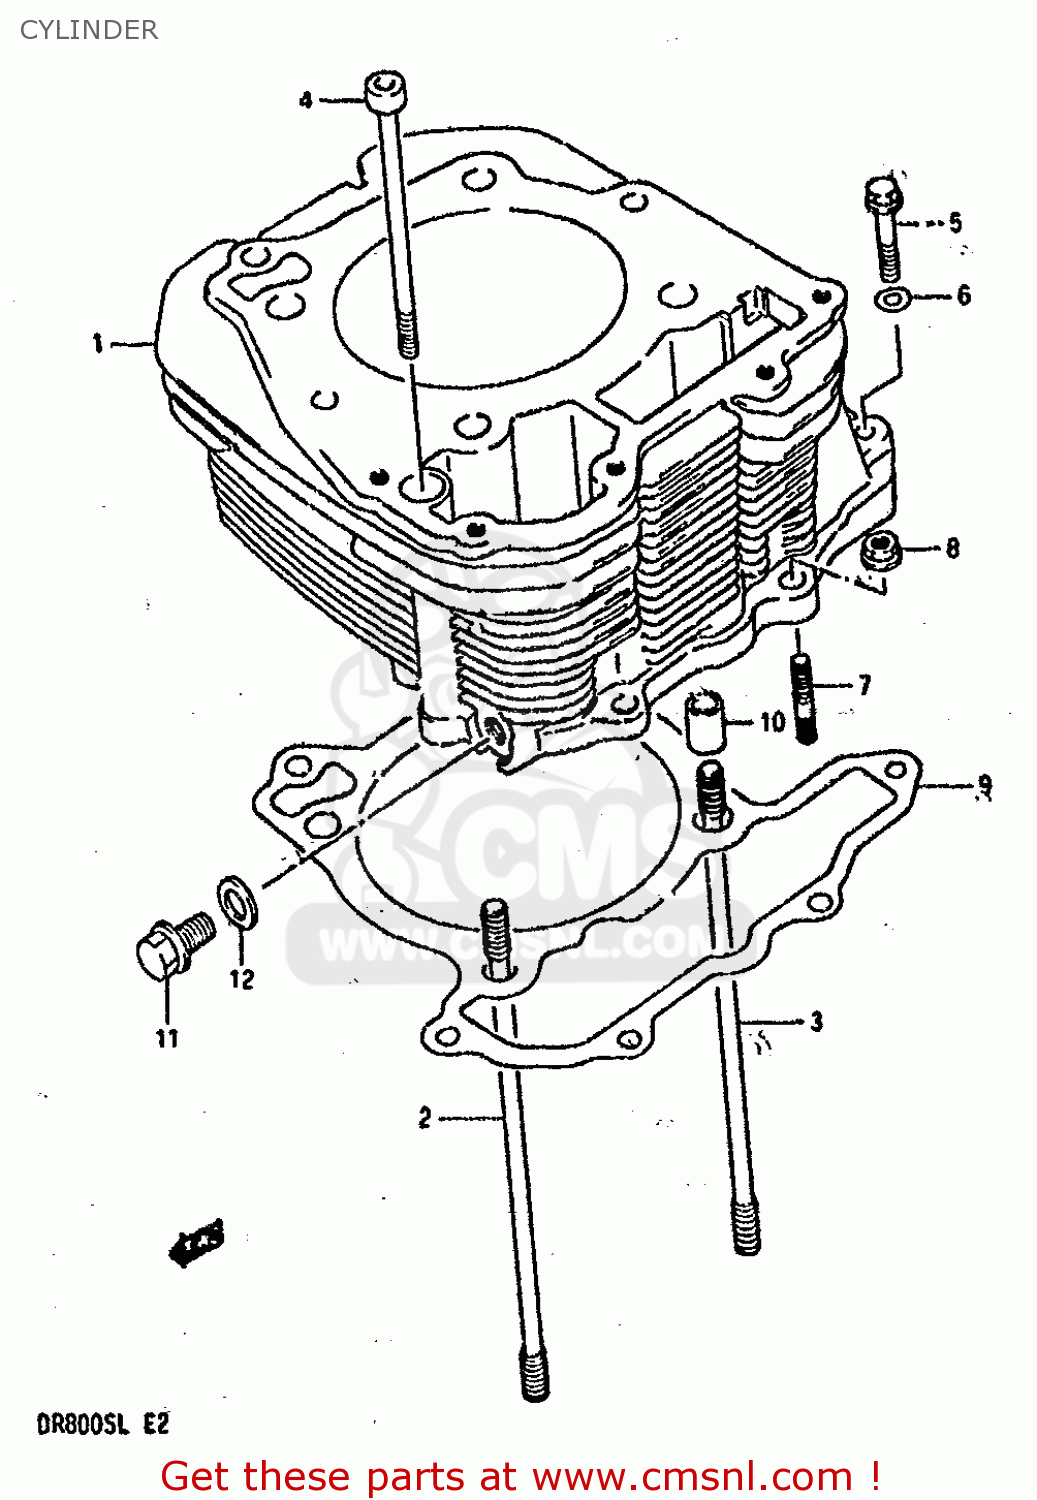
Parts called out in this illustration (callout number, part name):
1	CYLINDER (GRAY)
2	BOLT,STUD
3	BOLT,STUD(10X195)
4	BOLT L:115
5	BOLT
6	GASKET(5.8X13X1.2) (NAS)
7	STUD BOLT L:20
8	NUT 6MM
9	GASKET,CYLINDER (NAS)
10	PIN
11	BOLT
12	GASKET(10.2X20X2).3 (NAS)
